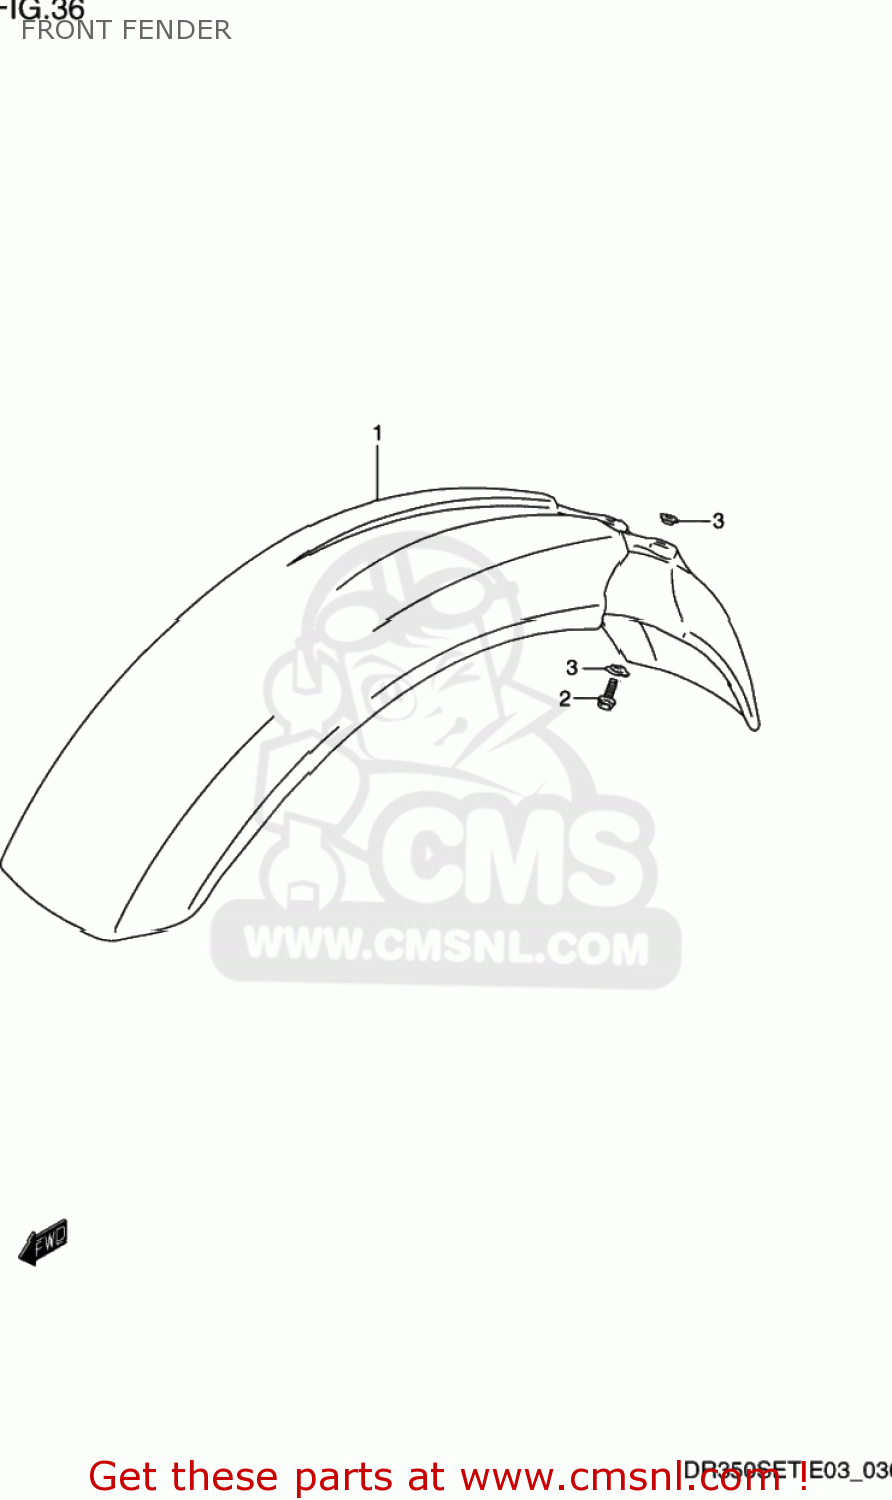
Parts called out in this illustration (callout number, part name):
1	FENDER,FR
2	BOLT
3	WASHER
